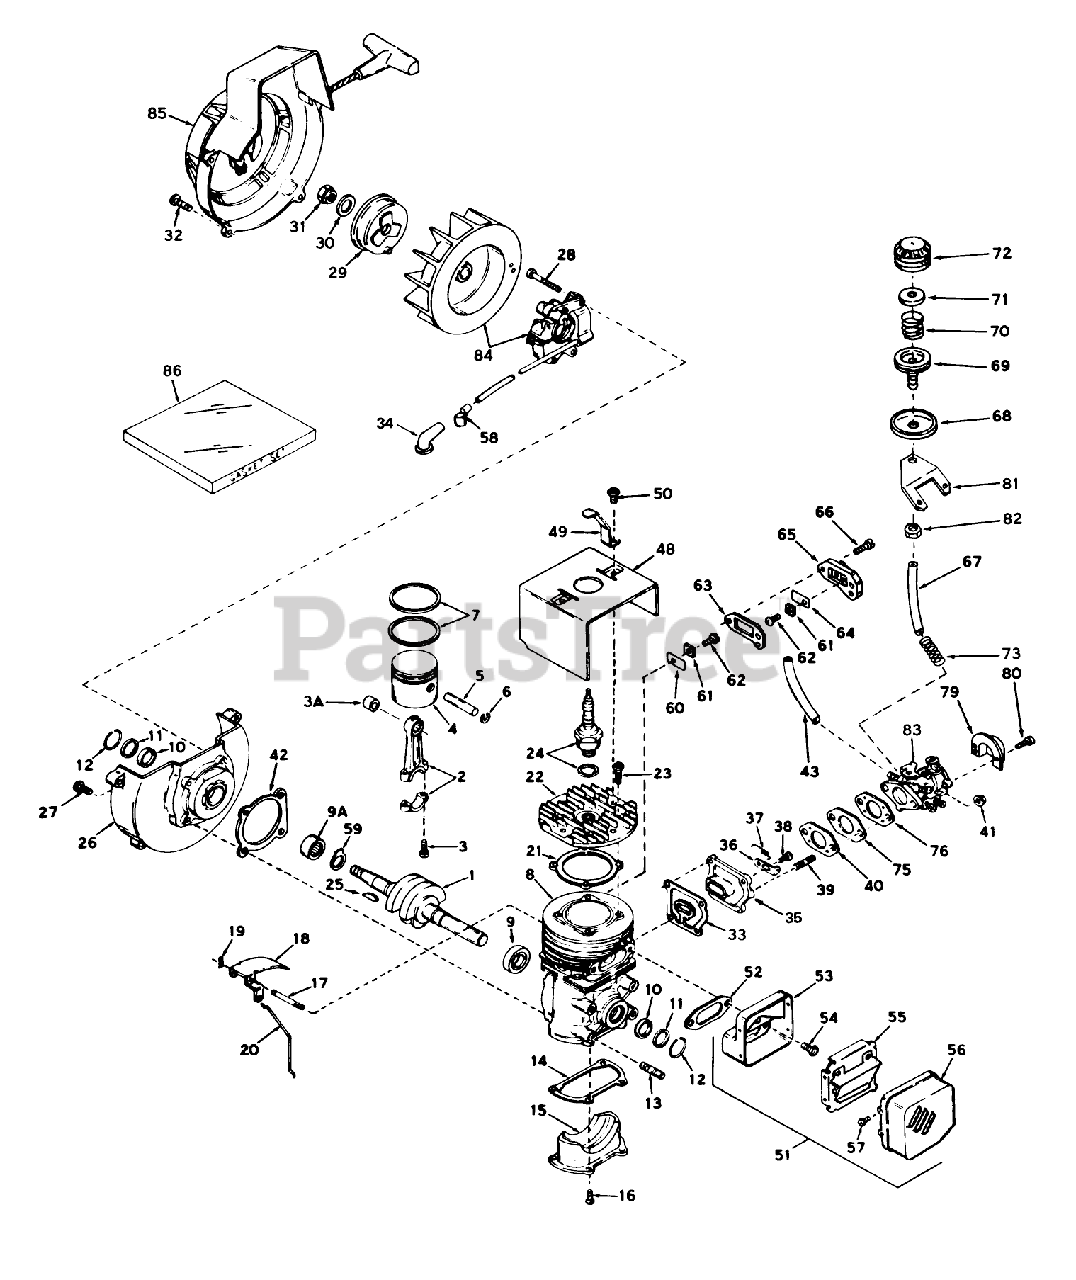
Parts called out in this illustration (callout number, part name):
1	Crankshaft
2	Rod Assembly, Connecting (Incl. Nos. 3 3A)
3	Bolt-Rod, Connecting
3A	Bearing-Cartridge
4	Piston
5	Pin, Piston
6	Ring-Retaning
7	Ring Set
8	Block Assy., Cylinder (Incl. Nos. 9, 10 thru 13 17)
9	Bearing Ball
9A	Bearing-Cartridge
10	Seal, Crankshaft
11	Retainer, Crankshaft Seal
12	Spring, Crankshaft Seal
14	Gasket, Cover
15	Plate, Cover
16	Screw (T-25, 10-24 x 1/2)
17	Shaft, Air Vane
18	Vane Assy, Air
19	Clip,Air Vane
20	Link Governor
21	Gasket, Cylinder Head
23	Screw (T-30, 1/4-20 x 3/4)
24	Plug, Spark (J17LM or equiv.)
25	Key, Woodruff
26	Base Assembly, Shroud (Incl. #9A-12)
27	Screw
28	Screw
29	Cup, Starter
30	Washer, Flat
31	Nut, Flywheel
32	Screw (T-30, 1/4-20 x 3/4)
33	Gasket, Port
34	51005 GIL.ROTARY TI
35	Adapter, Cover
36	Lever, Adjusting
37	Spring, Adjusting Lever
38	Screw
40	Gasket, Carburetor 1/8" thick)
41	Locknut
42	Gasket, Shroud Base
43	Line-Fuel (8.62)
48	Shroud, Cylinder
49	Lever, Stop
50	Screw (1/4-20 x 1/2)
51	Muffler Assembly (Incl. #53-57)
52	Gasket-Muffler
53	Base-Muffler
54	Screw
55	Baffle, Muffler
56	Cover, Muffler
57	Screw
58	Terminal, Lead wire
59	Washer, Thrust
60	Reed, Compression Release
61	Plate, Reed Hold Down
62	Screw
63	Gasket, Compression Release
64	Reed, Compression Release
65	Cover, Compression Release
66	Screw
67	Line, Primer
68	Retainer, Primer Bulb
69	Body, Primer
70	Spring, Primer Bulb
71	Washer, Primer Bulb
72	Bulb, Primer
73	Spring, Primer line support
75	Spacer
76	Gasket, Carburetor (1/16"thick)
79	Baffle-Carburetor
80	Screw
81	Mounting Bracket, Primer
82	Hex nut
83	Carburetor (Incl. #76)
84	BRACKET S
85	Shroud Starter Assy.
86	Gasket Set
